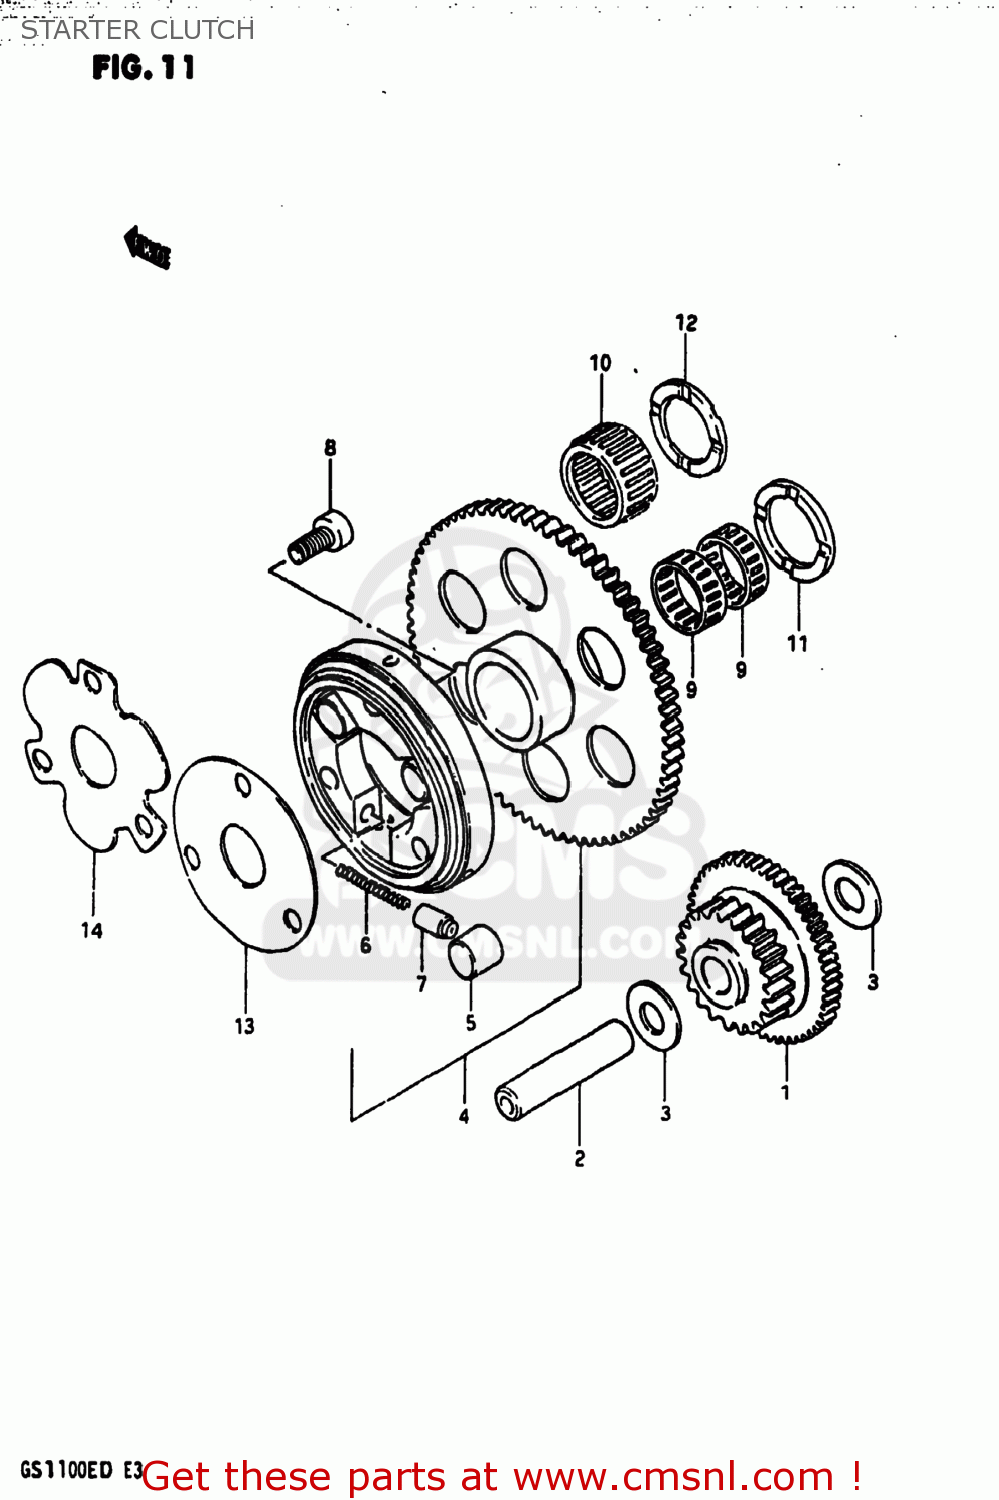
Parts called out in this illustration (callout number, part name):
1	GEAR,STARTER IDLE
2	PIN(7.4X13X56)
3	WASHER(13.3X25X0.85)
4	CLUTCH SET,STARTER
5	ROLLER(15X13)
6	SPRING
7	PIECE,PUSH
8	BOLT
9	BEARING
10	BEARING(29X35X24)
11	WASHER(25X38X2.5)
12	WASHER(29X41X2.5)
13	SHIM,STARTER CLUTCH HUB
14	SHIM,STARTER CLUTCH HUB
